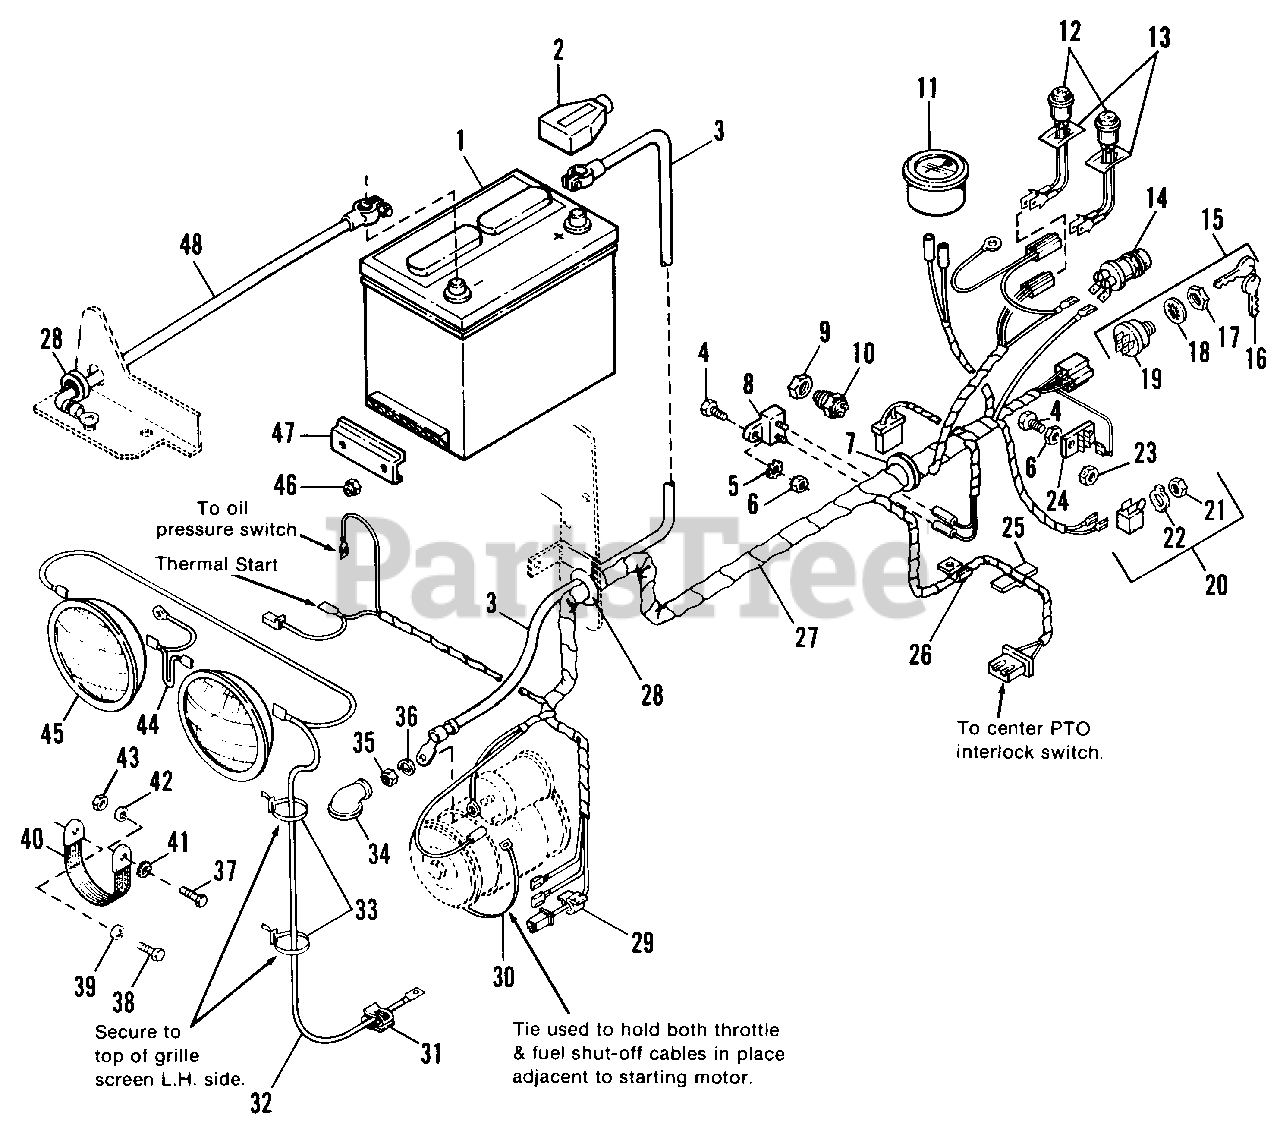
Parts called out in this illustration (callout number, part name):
1	BATTERY (Includes decal)
2	CABLE BOOT, Insulating
3	CABLE (Battery to Solenoid)
4	CAPSCREW, Hex Hd., 1/4-20 x 5/8
5	LOCKWASHER, Ext., 1/4
6	NUT, Hex, Full, 1/4-20
8	BREAKER, Circuit
9	NUT, Pal
10	SWITCH, Interlock
12	LIGHT, Indicator
13	NUT, Speed, Push on
14	SWITCH, Push Button
15	SWITCH & KEY ASSY., Ignition
16	KEY SET (2)
17	NUT, Special
18	LOCKWASHER, Int., 5/8
20	SWITCH, Toggle
21	NUT, Switch
23	LOCKNUT, Hex 1/4-20
24	BOARD, Terminal
25	CLIP, Wire
26	CLIP, Cable
27	HARNESS ASSY.
29	CLIP, Tinnerman
31	CLIP, Speed Cable
34	COVER, Terminal
35	NUT, Hex, M8
36	LOCKWASHER, M8
37	CAPSCREW, Hex Hd., 3/8-16 x 7/8
38	CAPSCREW, M10 x 1.5 x 25
39	LOCKWASHER, M10
40	STRAP, Ground (Engine to Ground)
41	LOCKWASHER, Ext. Tooth 3/8
42	LOCKWASHER, 3/8
43	NUT, Hex, 3/8-16
45	LAMP, Sealed Beam, G.E. #4411-1
46	NUT, Elastic 5/16-18
48	CABLE (Battery to Ground)
